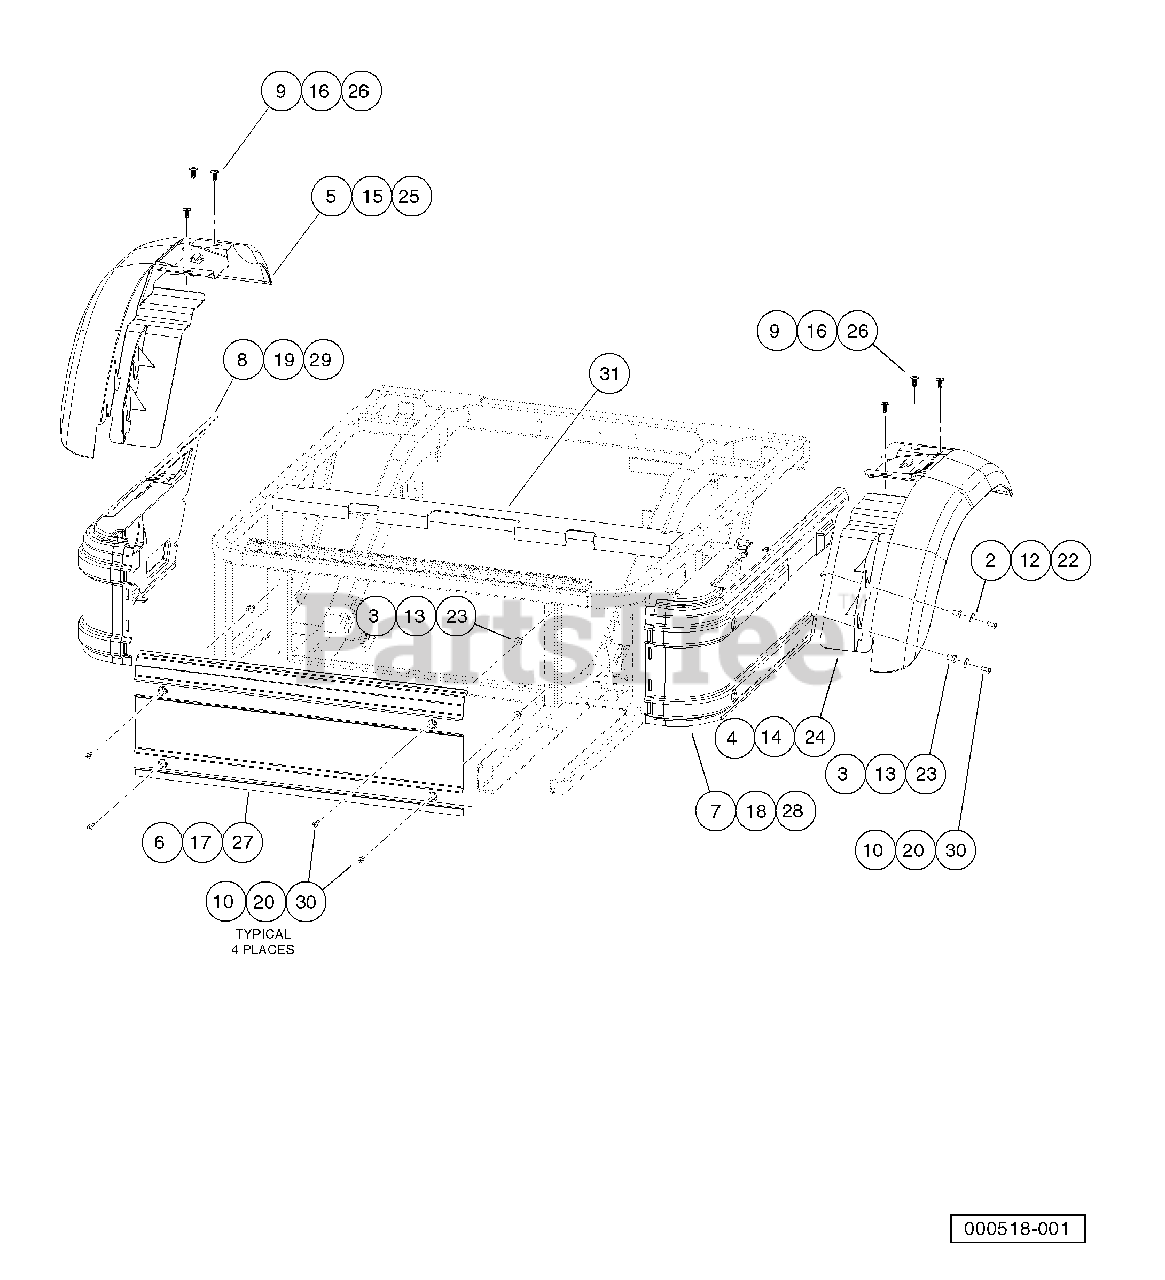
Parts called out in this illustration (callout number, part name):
1	Instl, Panels, Fenders, Blk
2	Washer, 1/4" Type B Flat
3	Well Nut 1/4-20
4	Left Rear Fender
5	Right Rear Fender
6	Panel, Front, Kick
7	Panel, Side, Molded, Driver
8	Panel, Side, Molded, Passenger
9	Screw, Tuflok, 10mm
10	Screw, 1/4-20 X 1.0 Truss-Head Machine
11	Instl, Panels, Fenders, Rthwd
12	Washer, 1/4" Type B Flat
13	Well Nut 1/4-20
14	Left Rear Fender
15	Right Rear Fender
16	Screw, Tuflok, 10mm
17	Panel, Front, Kick, Rthwhd
18	Pnl, Side, Mld, Drv, Rthwhd
19	Pnl, Side, Mld, Pass, Rthwhd
20	Screw, 1/4-20 X 1.0 Truss-Head Machine
21	Instl, Panels, Fenders, Moff
22	Washer, 1/4" Type B Flat
23	Well Nut 1/4-20
24	Left Rear Fender
25	Right Rear Fender
26	Screw, Tuflok, 10mm
27	Panel, Front, Kick, Moff
28	Pnl, Side, Mld, Drv, Moff
29	Pnl, Side, Mld, Pass, Moff
30	Screw, 1/4-20 X 1.0 Truss-Head Machine
31	Closeout, Extrusion
